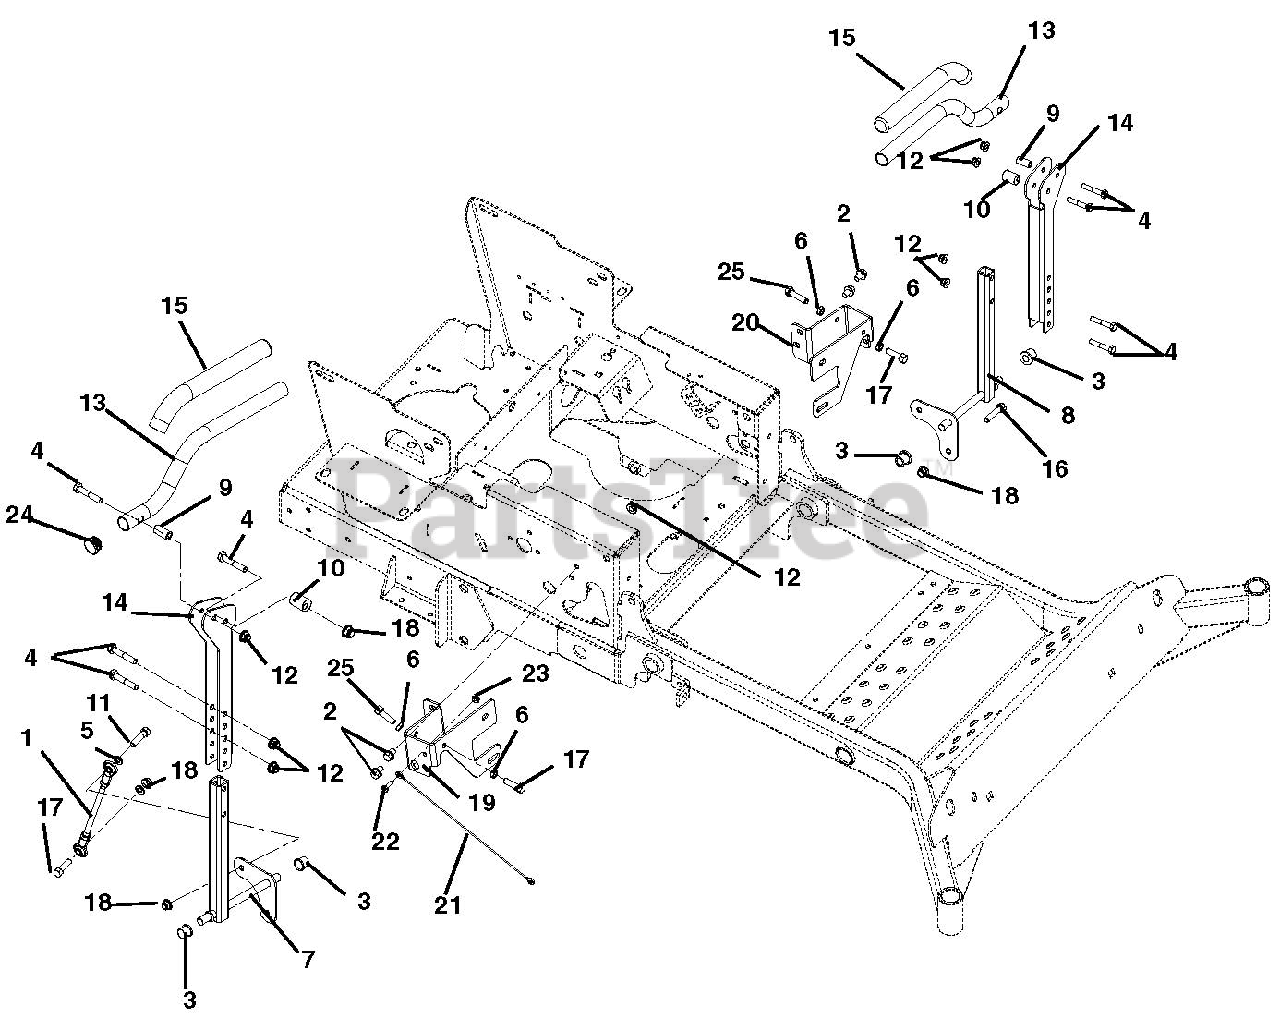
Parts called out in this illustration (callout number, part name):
1	Assembly, Steering Linkage
2	Screw, Tapping .38-16 x .50 Hex Washer Head
3	Bushing, Flange .515 x .750 x .745 x 1.00
4	Bolt, Hex .31-18 x 1.75 Grade 5
5	Washer, Locking .38 x .094
6	Nut, Hex Jam .375-16
7	Weldment, RH Control Arm
8	Weldment, LH Control Arm
9	Bushing, Spacer .330 x .505/.500 x 1.01
10	Bushing, Spacer .328 x .750 x 1.01
11	Bolt, Hex .38-16 x 1.50 Grade 5
12	Nut, Nyloc Flange .31-18
13	Handlebar, ZTXL
14	Bracket, Steering Control
15	Grip, Handlebar
16	Bolt, Hex .375-16 x 2.00 Full Thread
17	Bolt, Hex .38-16 x 1.25 Grade 5
18	Nut, Nyloc Flange 3/8-16
19	Stop, Steering-Right Hand
20	Stop, Steering-Left Hand
21	Cable, 12.0 LANYARD, Nylon
22	Bolt-Hex .25-20 x .75 Grade 5
23	Nut, Nyloc Flange .25-20
24	Caplug, Handlebar
25	Bolt, Hex .38-16 x .75 Grade 5
